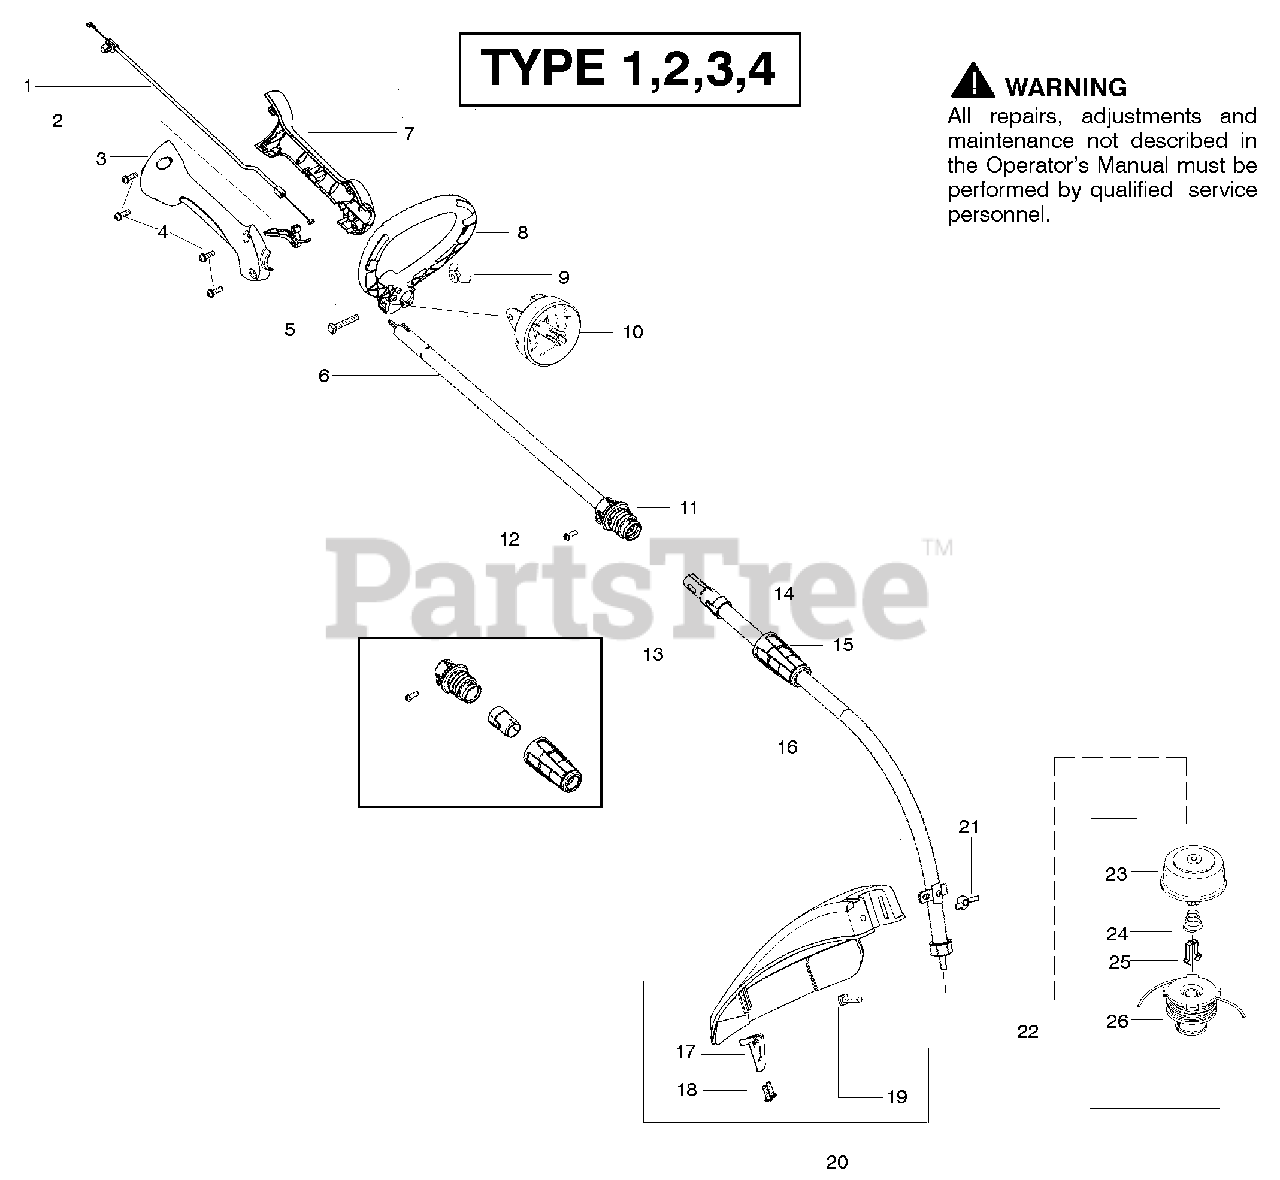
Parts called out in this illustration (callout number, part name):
1	Assy-Throttle Cable
3	Throttle Hsg. (Right)
4	Screw-Throttle Hsg.
5	Bolt-Handle
6	Kit-Drive Shaft
7	Throttle Hsg. (Left)
8	Assy-Handle
9	Wingnut
10	Spool Buddy
13	Kit-Coupler Shaft
16	Kit-Shaft Lower
17	Line Limiter
18	Screw-Line Limiter
20	Kit-Shield Assy
21	Wingnut
22	Accy-TNG VI Cutting Head
23	Assy-Hub
24	Spring-Compression
25	Clip-Retainer-Head
26	Accy- Spool w/Line
